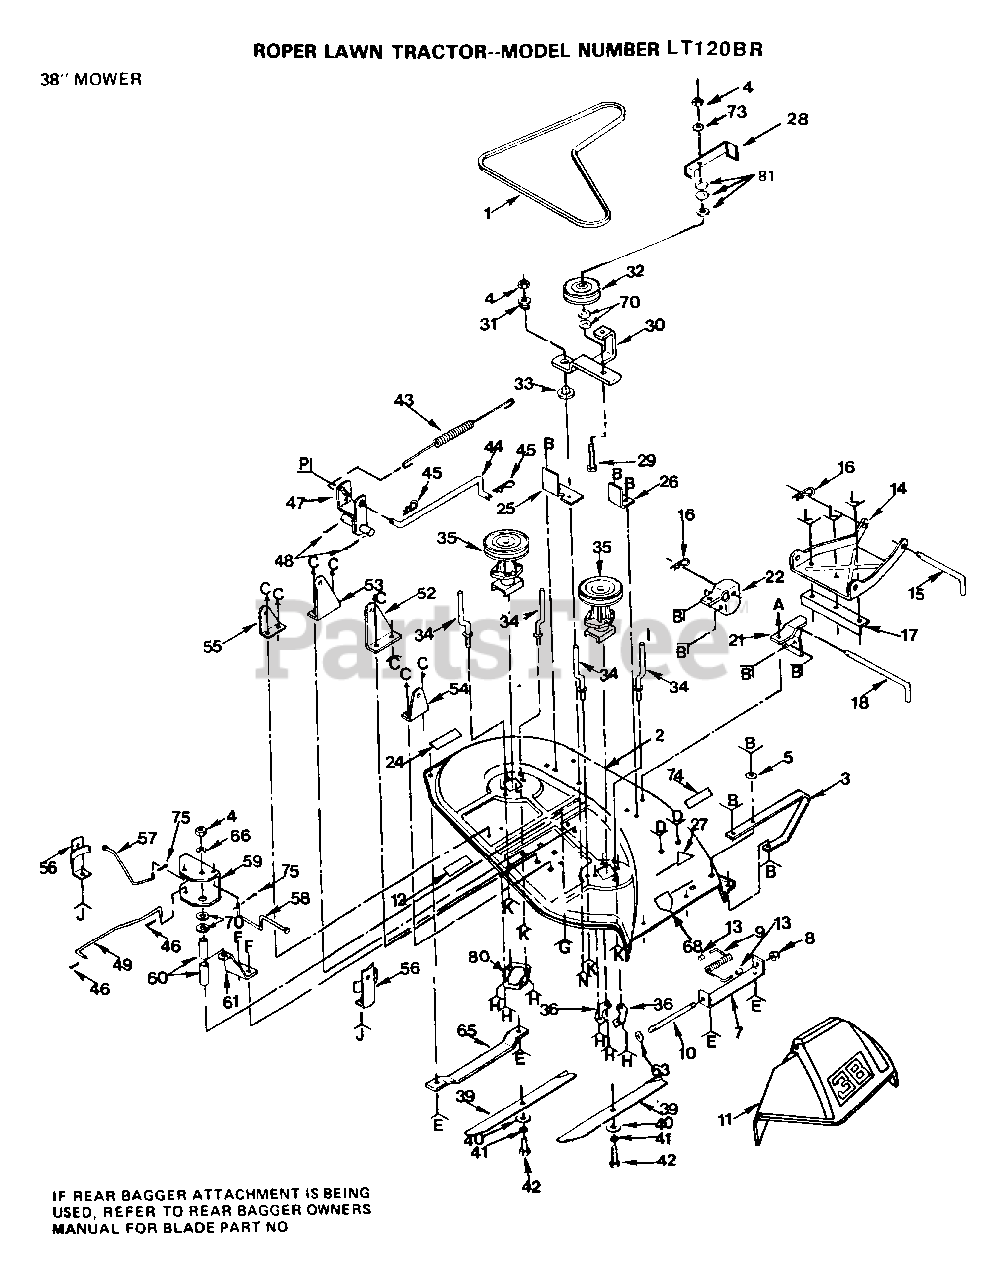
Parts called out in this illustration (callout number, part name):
1	BELT-V.79.1.MWR
5	WASHER M
8	NUT PUSH M
10	ROD-HINGE T
11	DEFLECTOR-SHLD T
12	DECAL.LT
13	CAP-SLEEVE LT
14	LINK.PARALLEL
16	SPRING.RETAINER
17	LINK STOP
21	BRACKET RH LT
22	BRACKET LH T
24	DECAL INSTRUCTION CAUTION
25	SUPPORT ARM T
26	STOP T
29	BOLT
31	SPACER RETAINER
32	IDLER-FLAT T
33	"WASHER, WEAR LT"
34	BELT KEEPER LT
36	SUPPORT PLATE LT
40	WASHER
42	No Desciption for Part
45	SPRING.RETAINER
47	ROCKSHAFT T
49	ROD BRAKE LT
54	"BRKT,SUSP RH T"
55	"BRKT,SUSP REAR LH"
56	BRAKE LT
58	ROD BRAKE LT
59	"BRK,BRAKE,PVT LT"
60	SPACER BRAKE LTV
61	BRACKET SUPT LTV
65	RUNNER-LH M
70	WASHER
73	WASHER
74	DECAL.WARNING.T
80	PLATE SUPPORT
